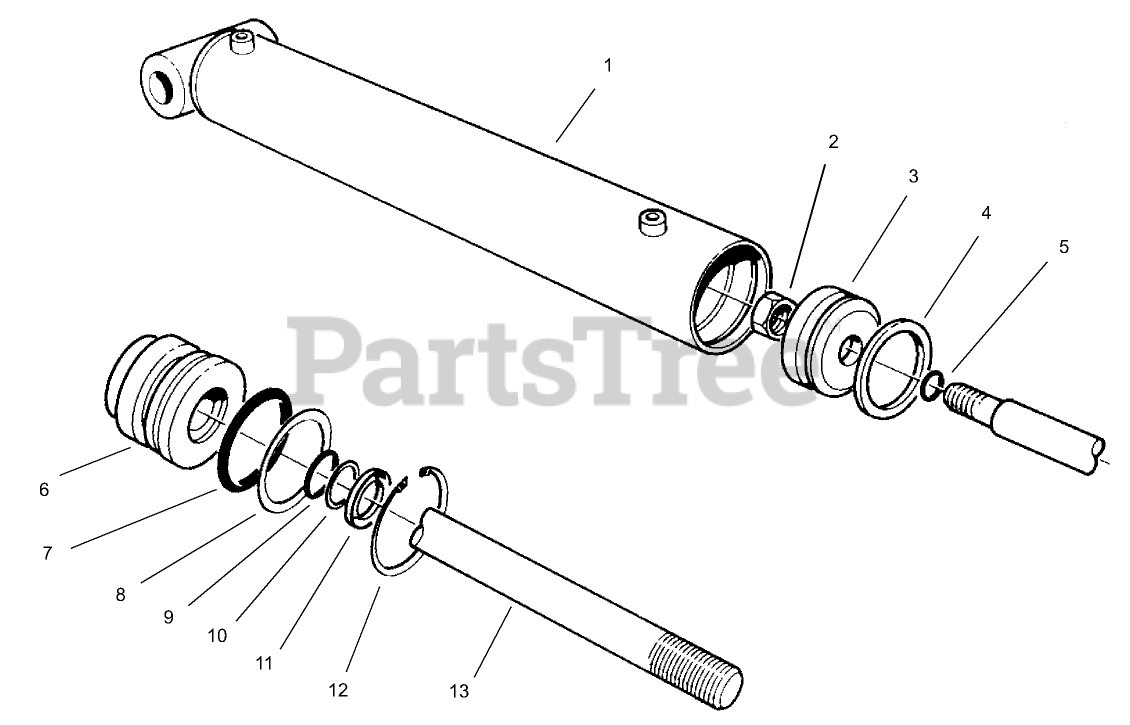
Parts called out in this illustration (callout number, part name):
1	Barrel
2	LOCKNUT
3	PISTON
4	Uniring
5	Seal-Dust
7	Seal-Dust
8	Washer-Backup
9	Seal-Dust
10	Washer-Backup
11	Seal-Dust
12	RING-RETAINING
13	SHAFT
